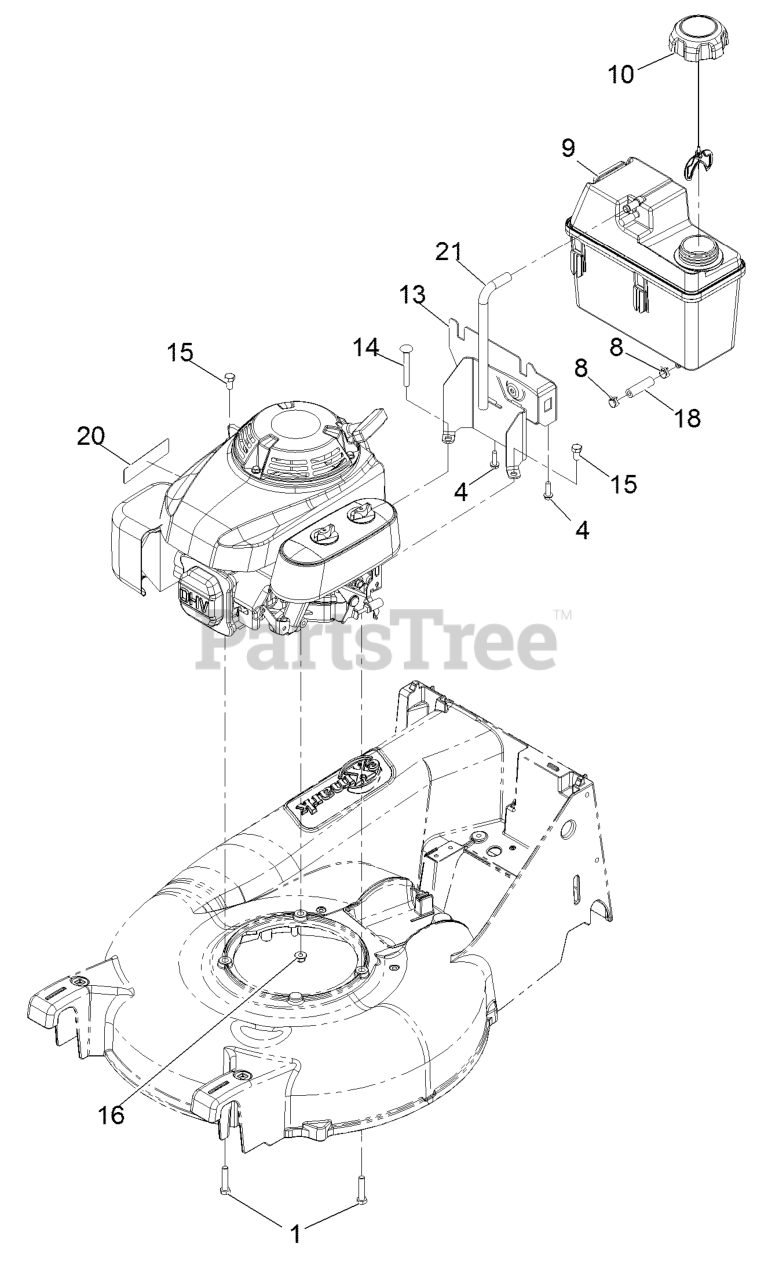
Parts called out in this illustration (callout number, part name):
1	SCREW-HH
4	SCREW-HWH
8	CLAMP-HOSE
9	TANK-FUEL
13	BRACKET ASM
14	SCREW-CARR
15	SCREW-HH
16	NUT-HF, NI
18	HOSE-FUEL
20	DECAL-ARRESTER, SPARK
21	HOSE-VENT, CANISTER
